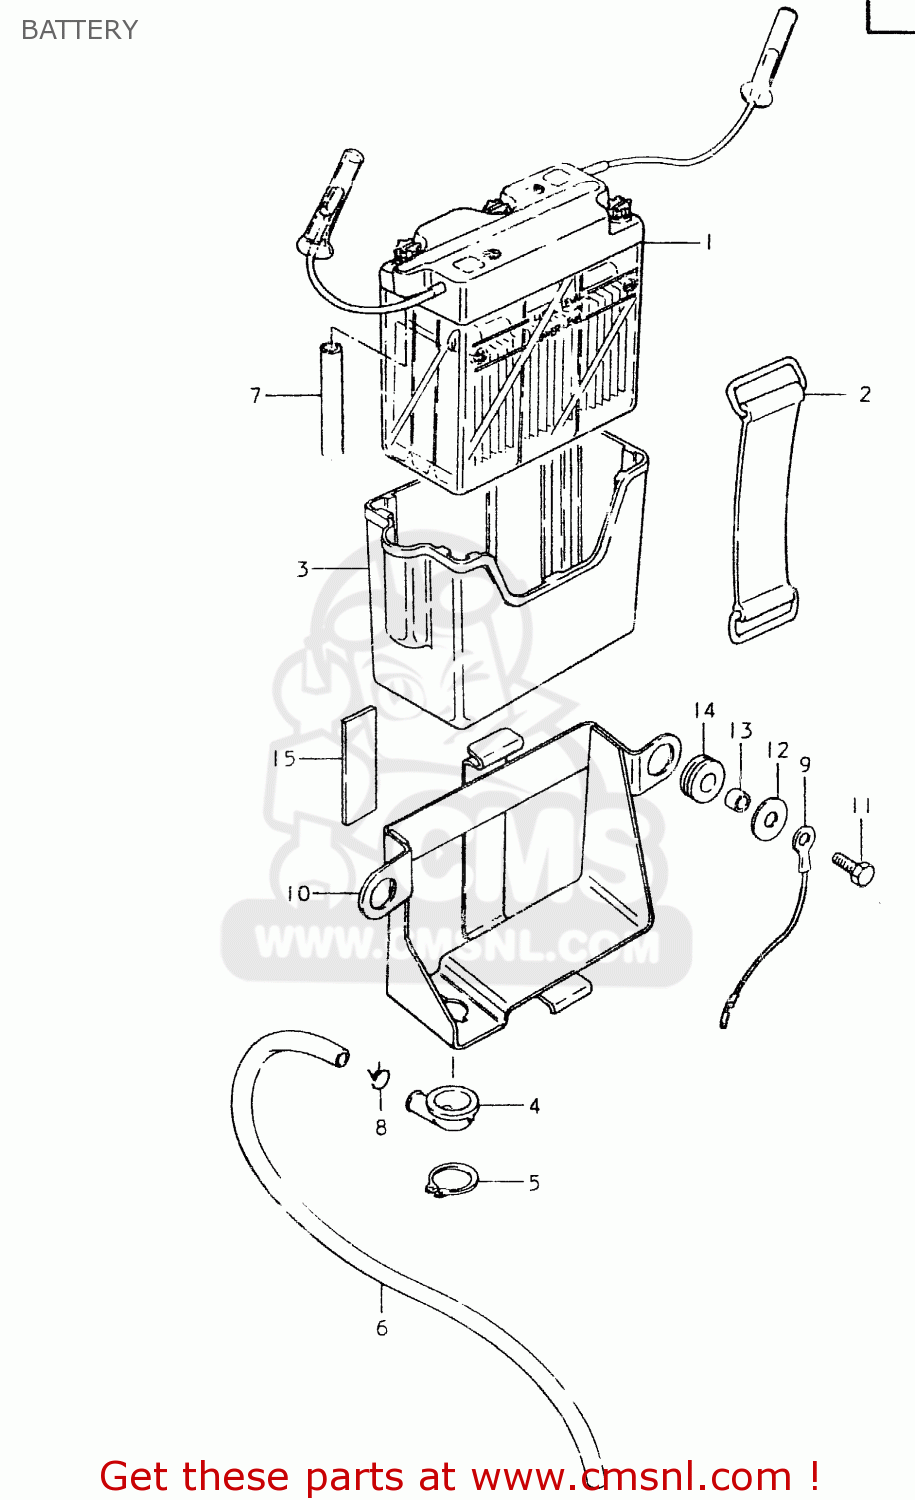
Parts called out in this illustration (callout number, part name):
1	BATTERY (6V, 4AH)
2	BAND
3	CASE,BATTERY
4	FUNNEL,BATTERY EXHAUST
5	CIRCLIP
6	HOSE,BATTERY EXHAUST
7	HOSE, EXHAUST (L:45)
8	CLIP
9	LEAD WIRE
10	HOLDER,BATTERY
11	BOLT
12	WASHER (6.5X20X1.2)
13	SPACER (7X9X7)
14	CUSHION
15	PROTECTOR,20X9
